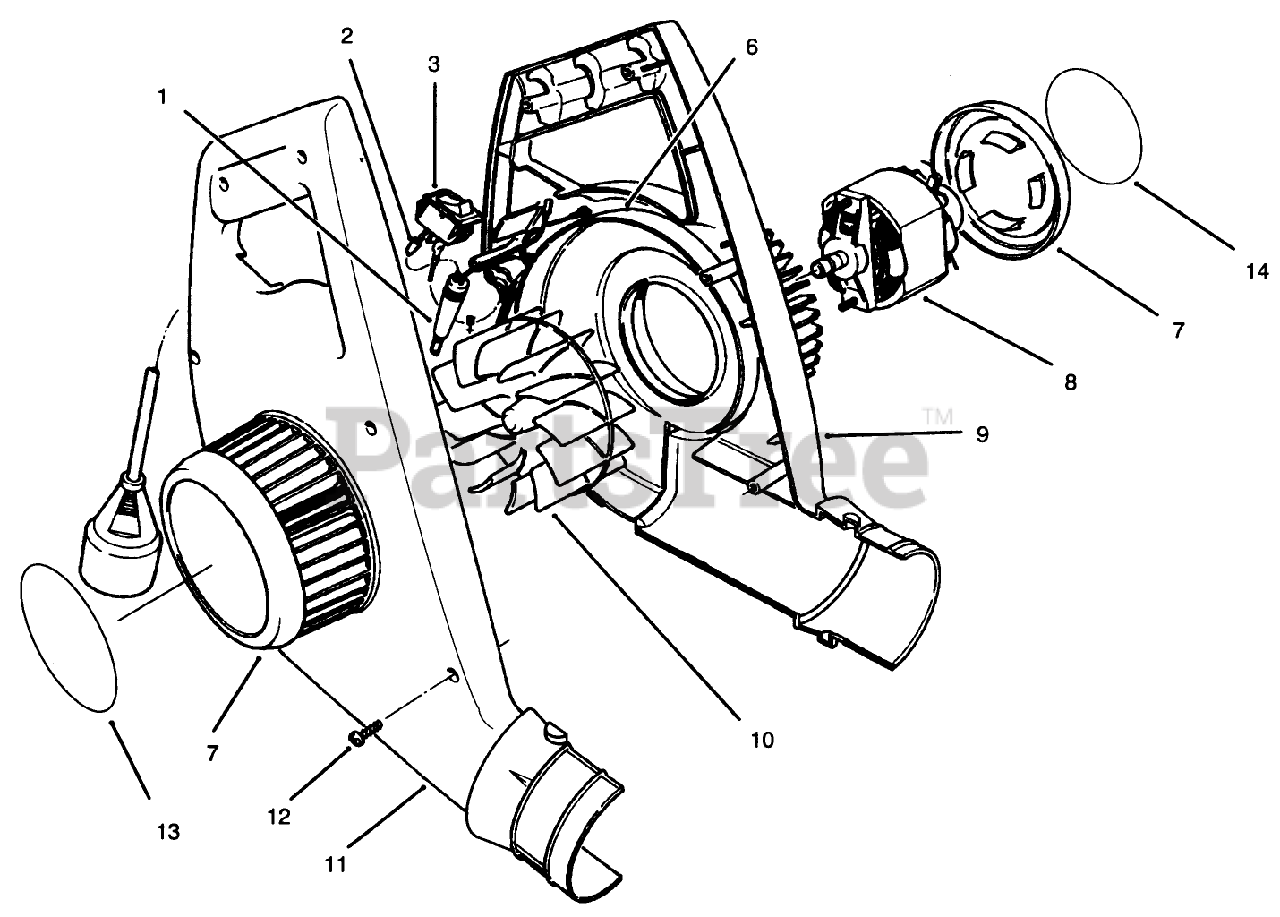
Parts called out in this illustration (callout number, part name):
1	POWER SUPPLY CORD
2	CONNECTOR-NUT, WIRE
6	MOTOR COVER - 300 BLO
8	MOTOR, 300 MINI-BLOWER
10	IMPELLER-MINI BLOWER
11	HOUSING RH - 300 BL
